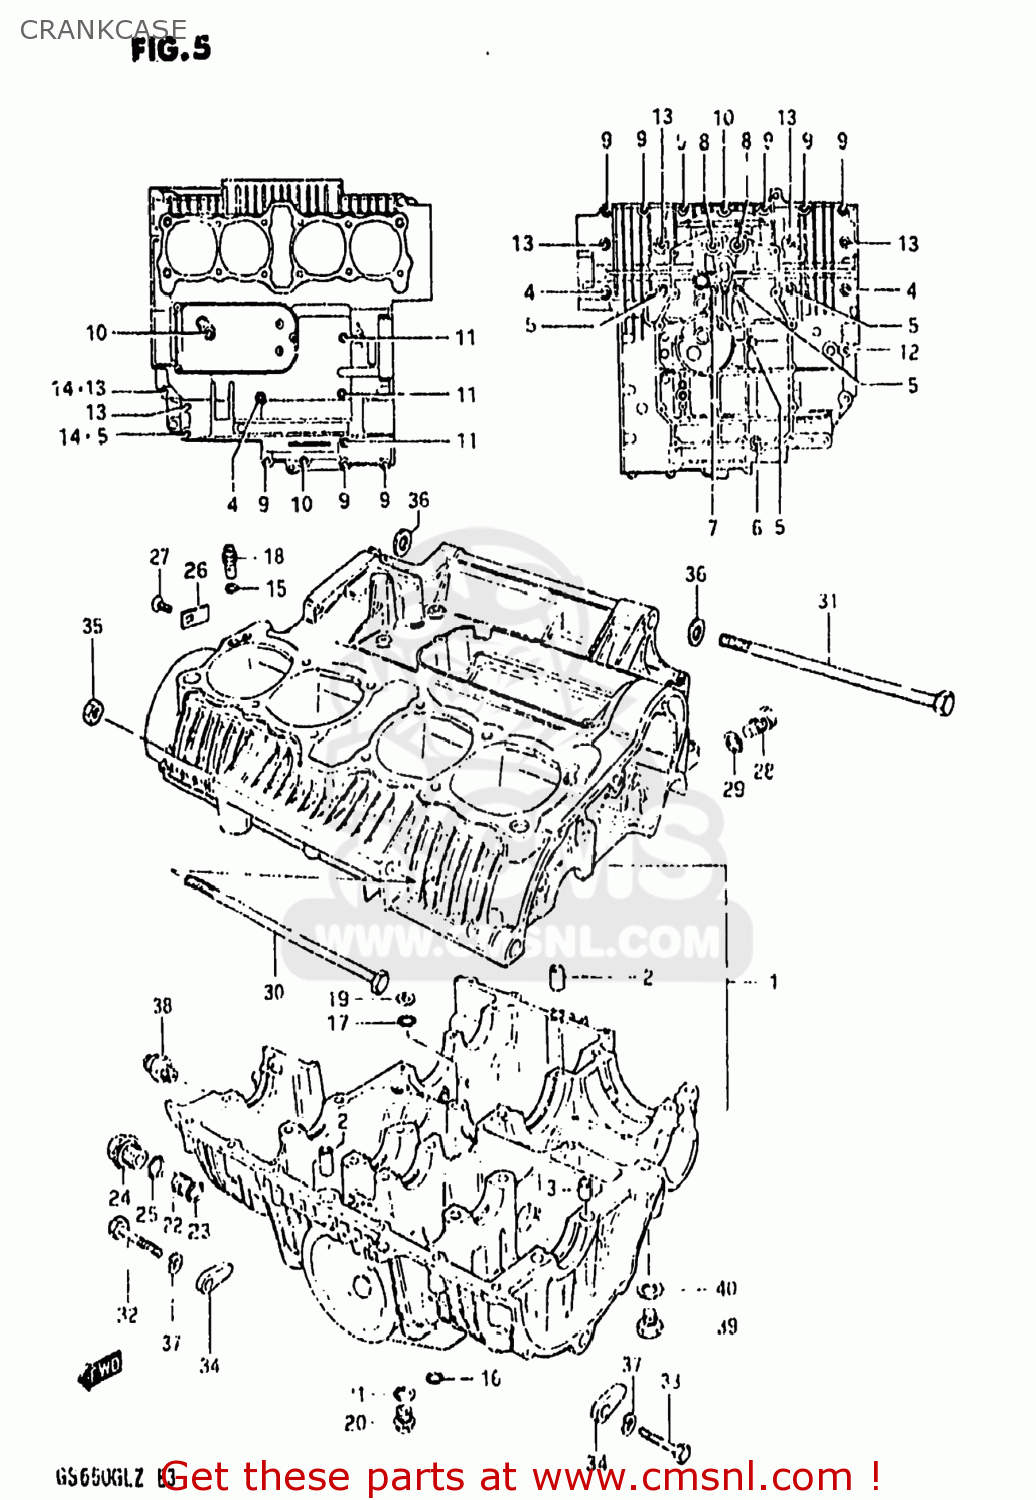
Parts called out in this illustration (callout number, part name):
1	CRANKCASE SET
2	PIN (11X20)(SUS)
3	PIN(10.4X13X22)
4	BOLT
5	BOLT
6	BOLT(8X135)
7	BOLT(8X140)
8	BOLT
9	BOLT
10	BOLT
11	BOLT (6X90)
12	BOLT (8X70)
13	BOLT (8X95)
14	NUT
15	O-RING,OIL GALLERY JET
16	O-RING
17	O RING(D:3.2,ID:12.9)
18	JET(12)
19	WASHER
20	PLUG
21	GASKET(16X22X2) (NAS)
22	PIN,OIL GALLERY
23	SEAL (D:1.9 ID:9.8)
24	PLUG
25	O RING(D:2.4,ID:17.8)
26	PLATE,OIL GALLERY PLUG
27	SCREW
28	PLUG
29	GASKET(12.1X16.2X3.7) (NAS)
30	BOLT
31	BOLT 10X250
32	BOLT 10X55
33	BOLT 10X40
34	NUT
35	NUT 10MM
36	WASHER
37	LOCK WASHER
38	SWITCH ASSEMBLY
39	PLUG
40	GASKET(14X19.2X2) (NAS)
